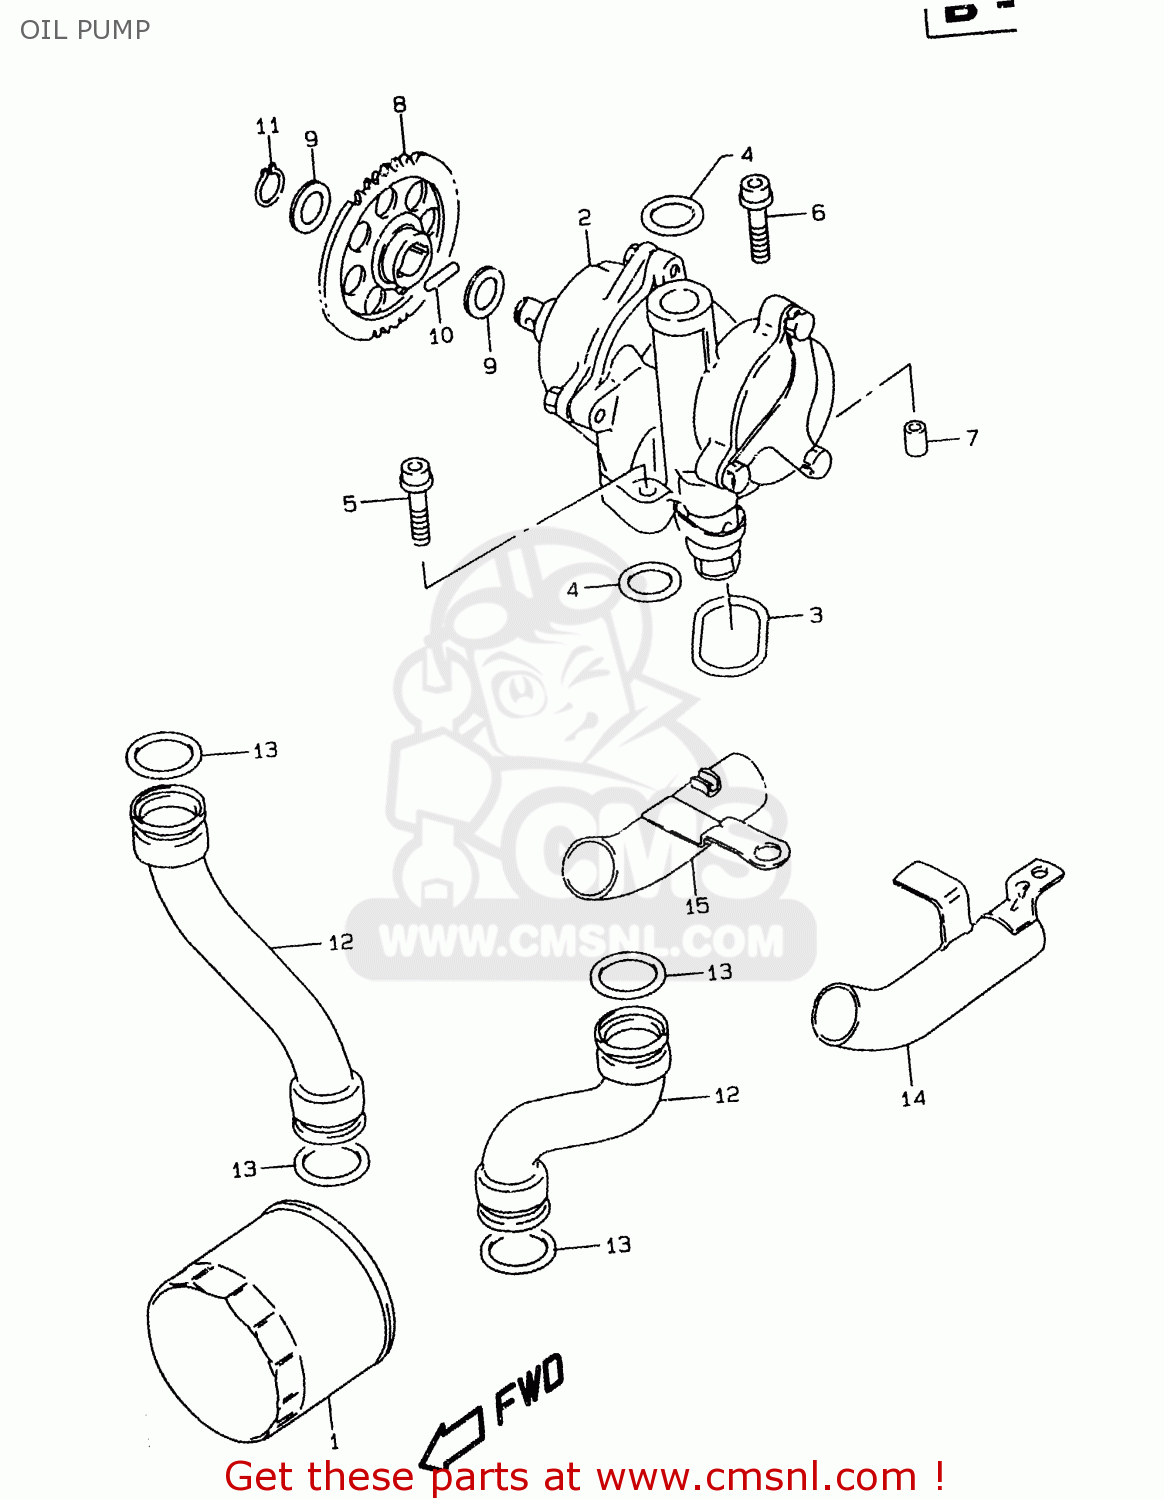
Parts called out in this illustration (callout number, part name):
1	FILTER ASSEMBLY,ENGINE OIL
2	PUMP ASSY,OIL
3	O RING,OIL PUMP
4	O RING(D:3.2,ID:17.8)
5	BOLT
6	BOLT
7	PIN
8	GEAR,OIL PUMP DRIVEN(NT:37)
9	SHIM
10	PIN(5X18)
11	CIRCLIP,12 MM
12	PIPE,OIL OUTLET
13	O RING(D:3.7,ID:21.7)
14	PIPE,OIL OUTLET UNDER,L
15	PIPE,OIL OUTLET UNDER,R
